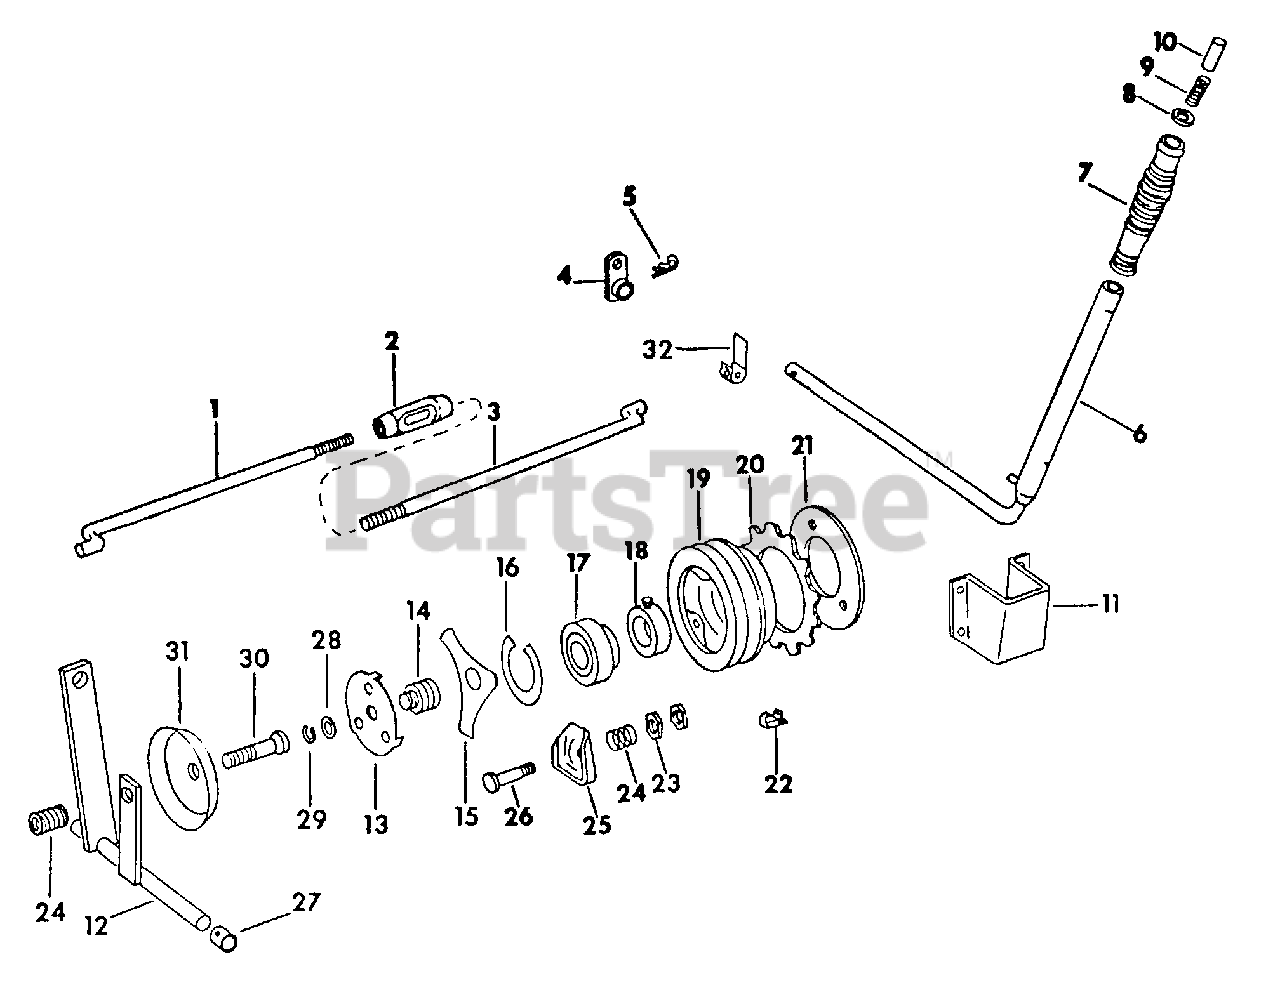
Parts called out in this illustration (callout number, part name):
2	Turnbuckle, Rod
3	Rod, Rear Clutch
4	Lever Assy, Pivot
5	Pin, Quick Attachable Cotter
6	Handle Assy, PTO
8	Washer, Release Rod Spring
9	Spring
10	Pin, Handle Release Rod
11	Bracket Assy, PTO Handle
12	Rockshaft Assy, PTO Clutch
13	Disc, IPTO Brake
14	Button, Thrust
15	Spring, Pressure
16	Ring, Snap 2.197 O.D., for Pulley
17	Bearing w/Ring IH-60072-C1, Ball
18	Collar w/Set Screw & Lock Nut, Bearing
19	Pulley, Mower Actuating
20	Disc, Friction
21	Plate, Pressure
22	Spring, Disc
23	Nut, 1/4-28 Hex Jam
24	Spring, Compression
25	Lever, Throw-Out
26	Screw, Special Machine
27	Bushing, Rockshaft
28	Washer, Curved Spring
29	Ring, Retaining
30	Screw, Brake Shoe Pivot
31	Shoe Assy, IPTO Brake
32	Spring, Actuating
